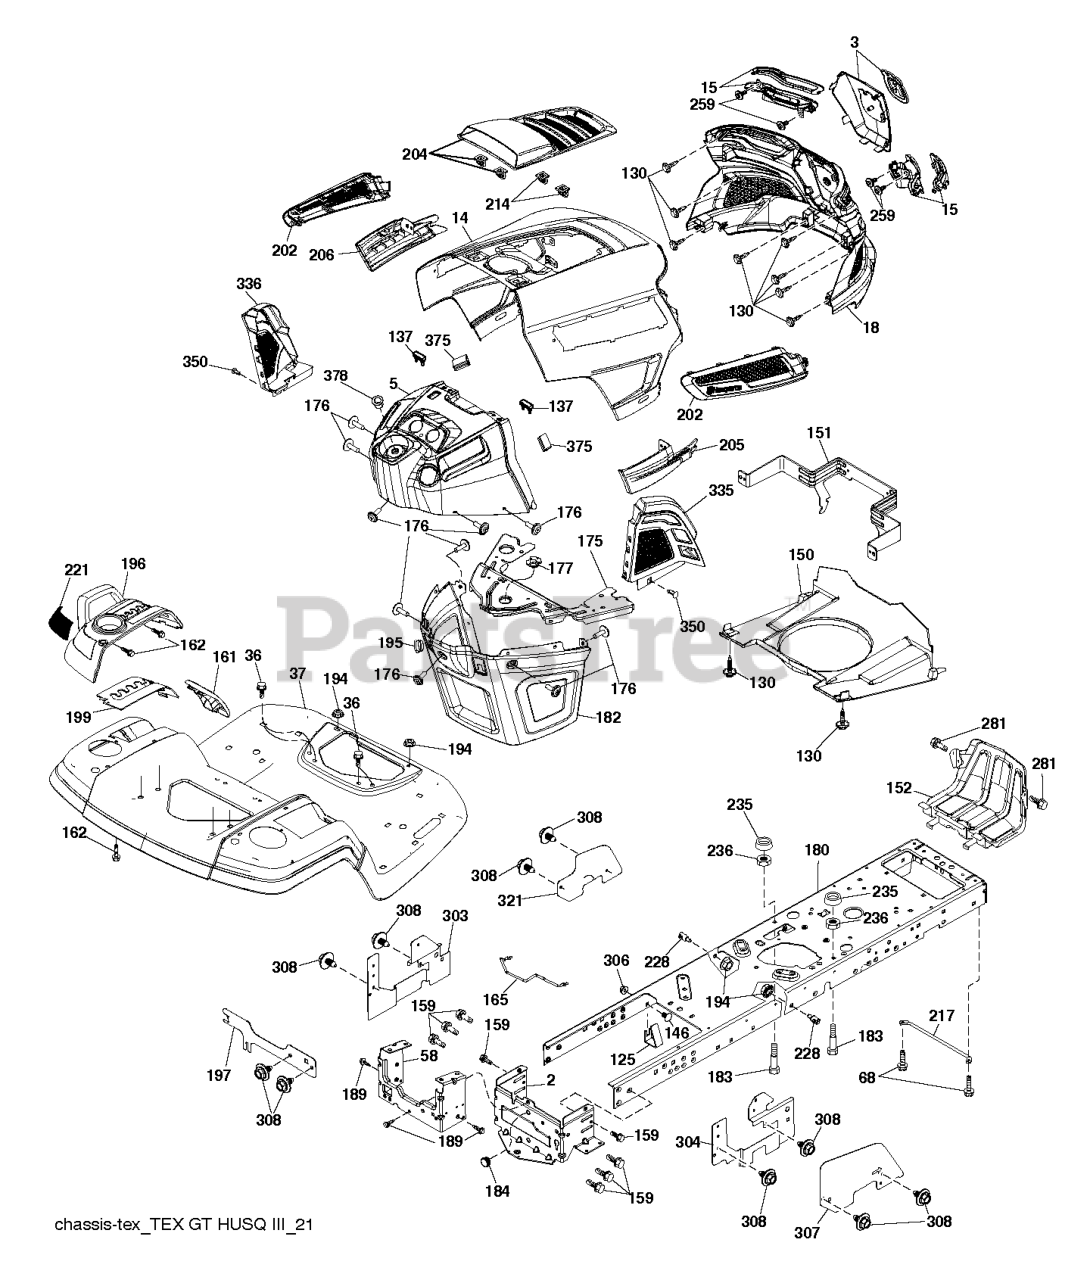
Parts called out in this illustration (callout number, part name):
2	DRAWBAR.LOWER.2PC.18/22
5	DASH.UPPER.ASM.GT2.DR.EL.EFM
14	HOOD.ASM.HUSQVARNA.GT.TEX.ORAN
15	Service Kit
36	SCREW 5/16"
37	FENDER.PNT.TX.GT.CH/FW/DL.HUSQ
58	DRAWBAR.UPPER.2PC,LRG.FENDER
125	CLIP.FUEL.LINE
137	BUMPER DASH
146	BOLT.RDHD.SHT.SQNK.3/8-16X5/8
150	AIR.DUCT.GTV.BLACK
151	BRACKET.PIVOT.HOOD.GT.HUSQ.II
152	SHIELD.BROWNING.PNT.GT.V2
159	SCREW, 3/8-16X3/4
161	CONSOLE.WINDOW.FUEL.HUSQ.GT
165	SUPPORT.TANK.REAR.B/TE
175	PLATE.PNT.CROSSMEMBER.HUSQ/PRE
176	SCREW.#10-24X5/8.RN.QU
177	BUSHING STEERING
180	CHASSIS.LT/GT.BOLTED
182	DASH.LOWER.COMMON.12V.ADAPTOR
184	PLUG.DEMO.625
189	SCREW
195	PLUG.HOLE.DASH.LOWER.12V.BLK
196	SUBASM.CONSOLE.HUSQ.GT.DECKLFT
197	SHIELD.DRAWBAR.LT.REAR.TANK
199	PLATE.DECK.LIFT.HUSQVARNA.GT
205	SIDE.TRIM.RH.GT.HUSQ.II
206	SIDE.TRIM.LH.GT.HUSQ.II.GRAY
214	CLIP.RETAINER.TINNER.
217	ROD.PIVOT.HOOD
221	REFLECTOR.LH.TEX GT HU
228	STUD.W/"D"ANTI-ROTATION
236	NUT.CENTERLOCK.5/16-
281	SCREW 3/8-16X1
303	SHIELD.LWR.LH.LTGT.NON30
304	SHIELD.LWR.RH.LTGT.NON30.NOTCH
306	NUT LOCK FLG 3/8-16 UNC
307	SHIELD.UPPER.RH.GT
308	BOLT.5/16-18UNCX3/4 W/SEMS.BLK
321	SHIELD.UPPER.LH.GT
335	COVER.LOWER.DASH.RH.BLACK
336	COVER-LH.LOWER.DASH.GT2.BLACK
350	CLIP.X-MAS.TREE
375	BUMPER CLIP-ON. DASH 1"
378	BUSHING FLANGE; PLASTIC
